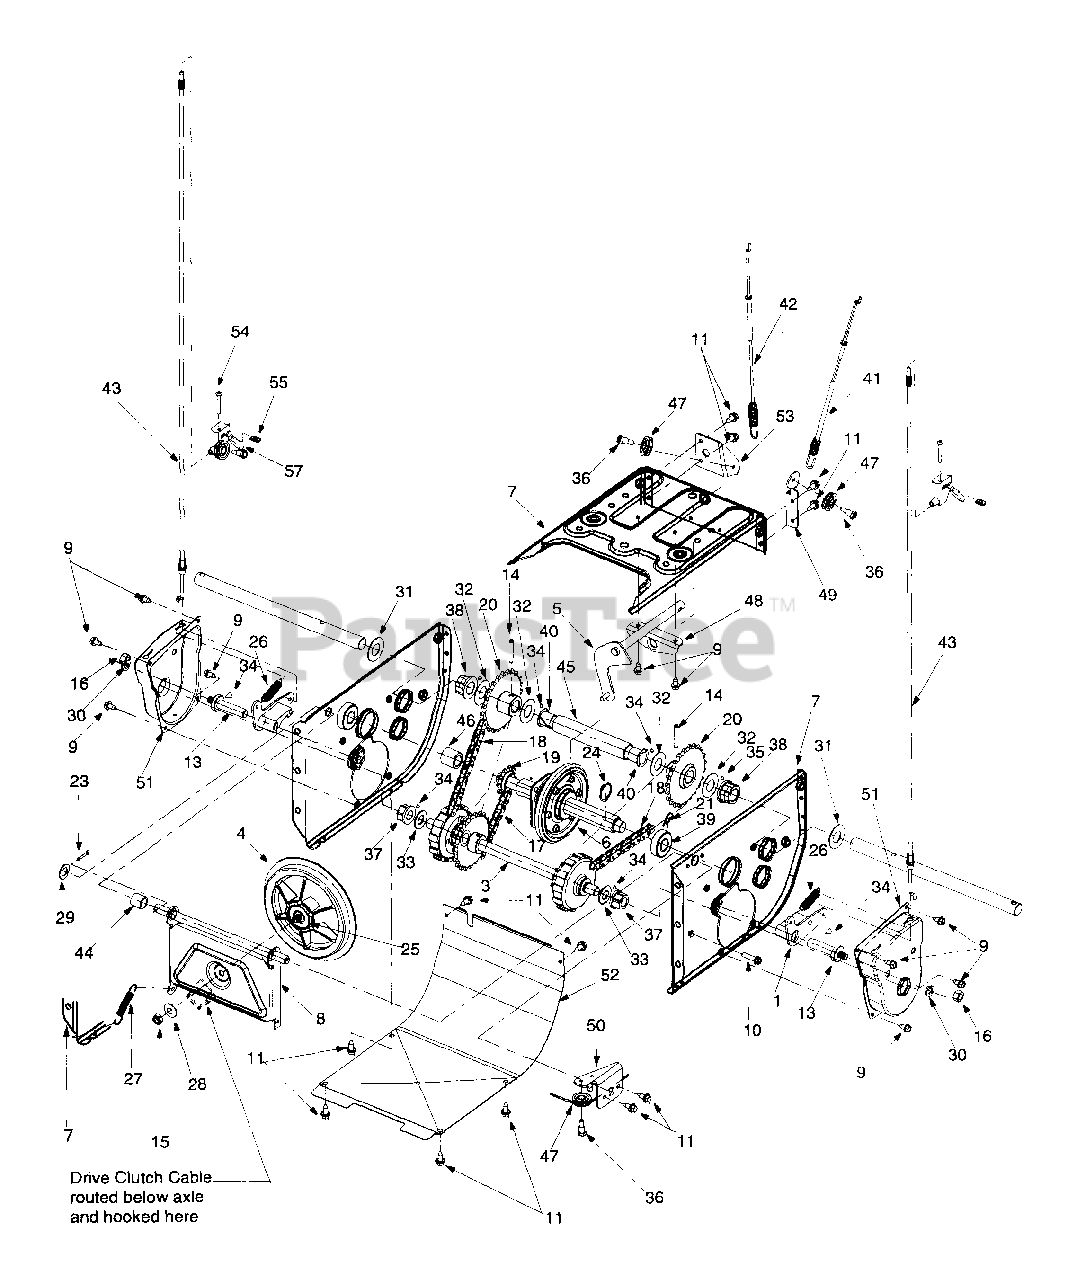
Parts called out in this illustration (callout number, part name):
1	Dogg Assembly: RH
2	Dogg Assembly: LH
3	Shift Assembly: Steerable Drive
4	Friction Wheel Disc Assy.
6	Friction Wheel Assembly, Complete
10	Hex Washer Hd. Tl Screw 1/4-20 x 1.0"
11	Hex Washer Hd. TT Screw 1/4-20 x .625"
12	Drive Shaft
13	Actuator Shaft
15	Jam Nut 3/8-24 Gr.8
16	Hex Nut: 3/8-16
17	Chain
18	Chain
19	Sprocket: 10T
20	Sprocket
21	Cotter Pin
23	Cotter Pin
24	Snap Ring
25	Adhesive: Loctite
26	Extension Spring
27	Extension Spring
28	Bell Washer
29	Flat Washer
30	Lock Washer
31	Flat Washer
32	Flat Washer
33	Flat Washer
34	Lubricant: 6 in 1
35	Grease
36	Shoulder Screw
37	Hex Flange Bearing
38	Hex Flange Bearing
39	Ball Bearing
40	Flange Bushing
41	Auger Clutch Cable
42	Drive Clutch Cable
43	Steering Cable
44	Spacer
45	Support Tube: Axle
46	Spacer
47	Roller Cable
55	Weld Nut
56	Cable Tie
57	Turn Trigger
58	Cotter Pin
